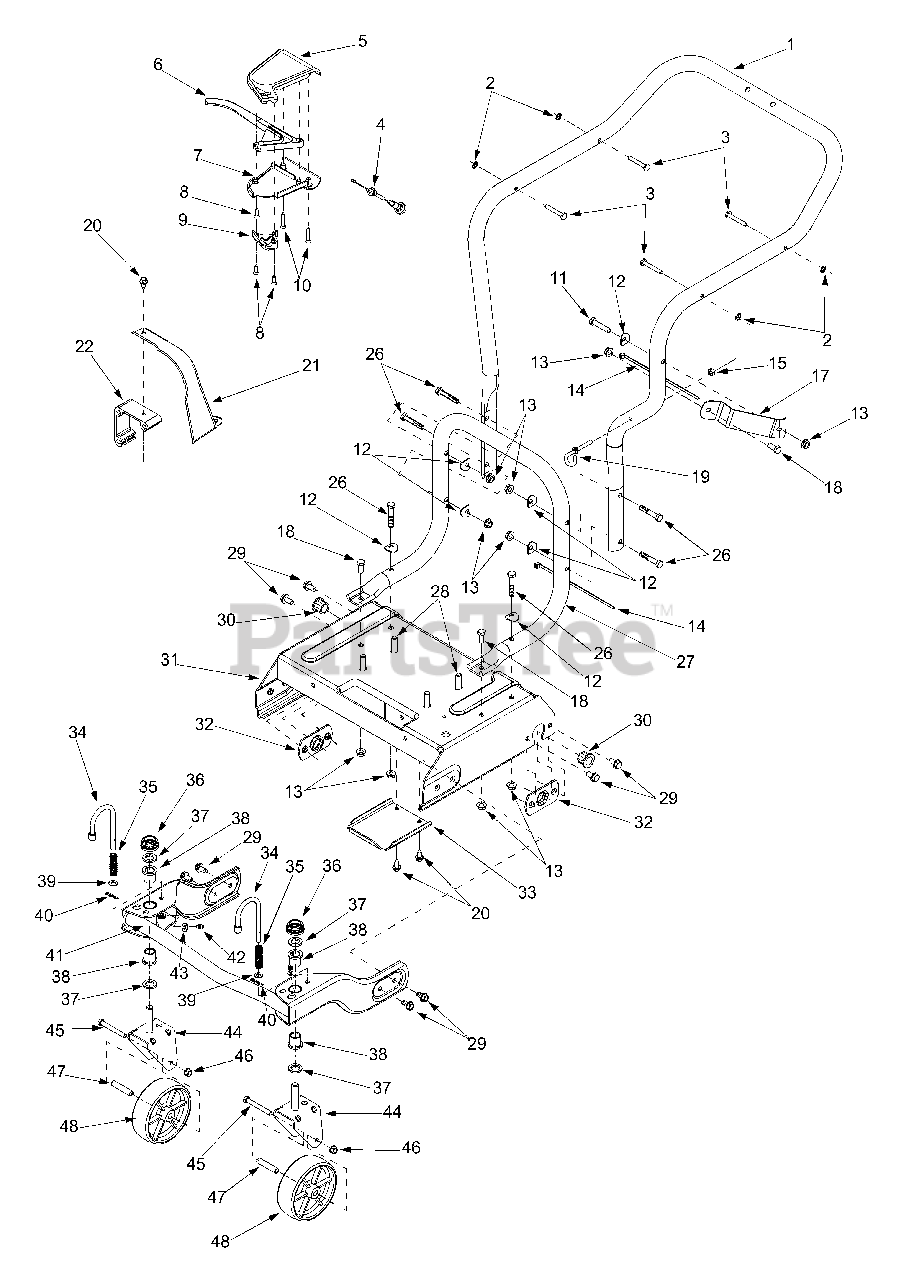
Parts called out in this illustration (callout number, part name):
2	Push Nut
3	Stud Pin.250 x 1.75
4	Clutch Cable 56"
5	Upper Clutch Cover
6	Drive Lever
7	Lower Clutch Cover
8	Screw #10-12 x.750
9	Cable Mounting Cap
10	Screw #10-16 x 1.25
11	Hex Cap Screw 5/16-18 x 1.50
12	Shoulder Washer.320 ID x.93 OD
13	Hex Flange Lock Nut 5/16-18
14	Cable Tie
15	Hex Nut 1/4-28
18	Hex Cap Screw 5/16-18 x.75
19	Eye Bolt
20	Self Tapp. Screw 1/4-14 x.625
21	Belt Cover
22	Engine Mounting Adapter
26	Hex Cap Screw 5/16-18 x 1.75
28	Screw 3/8-16 x 1.25
29	Hex Washer Screw 5/16-18 x.625
30	Hex Flange Bearing.631 x.720
34	Lock Pin
35	Compression Spring
36	Push Cap
37	Flat Washer 5/8 ID x 1.0 OD
38	Flange Bearing.632 ID
39	Flat Washer.330 ID x.630 OD
40	Cotter Pin
42	Grease Fitting 3/16
43	Flat Washer.203 ID x.403 OD
45	Hex Cap Screw 3/8-16 x 3.0
46	Flange Lock Nut 3/8-16
47	Spacer
48	Wheel 6.0 x 2.0
